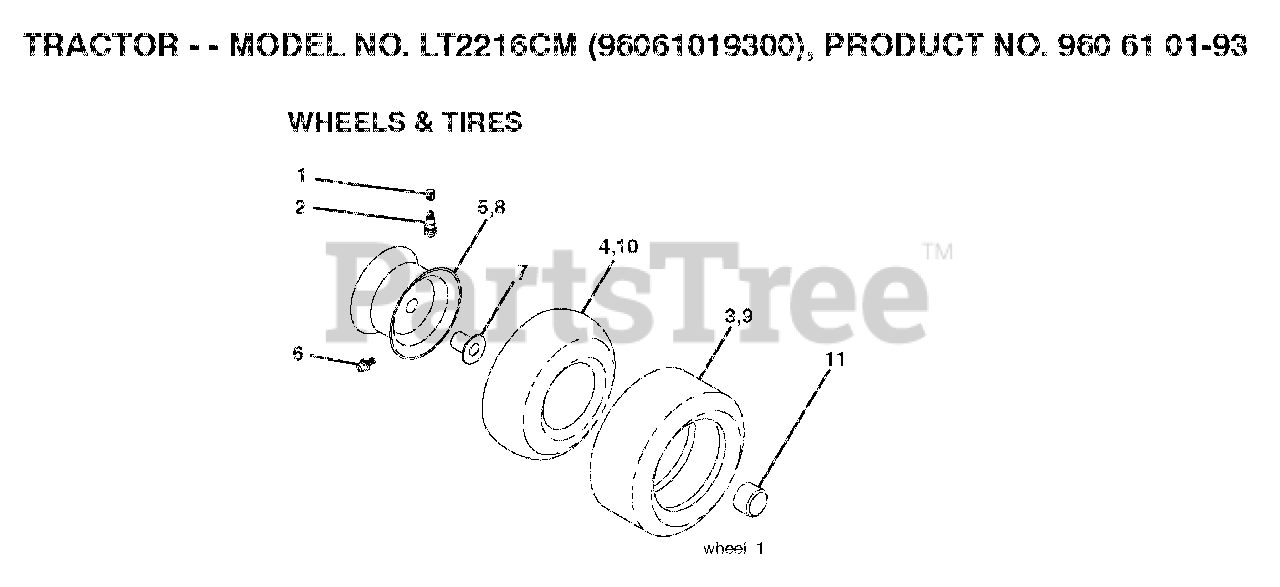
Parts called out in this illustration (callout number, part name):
1	VALVE CAP
2	VALVE STEM LT
3	TIRE HEAVY DUTY
4	TUBE.5.3/4.5/6
5	RIM ASM 6" FRONT SILVER
6	FITTING LT
7	BEARING T
8	RIM ASM 8" REAR SILVER
9	TIRE HEAVY DUTY
10	TUBE
11	CAP, AXLE BLK
